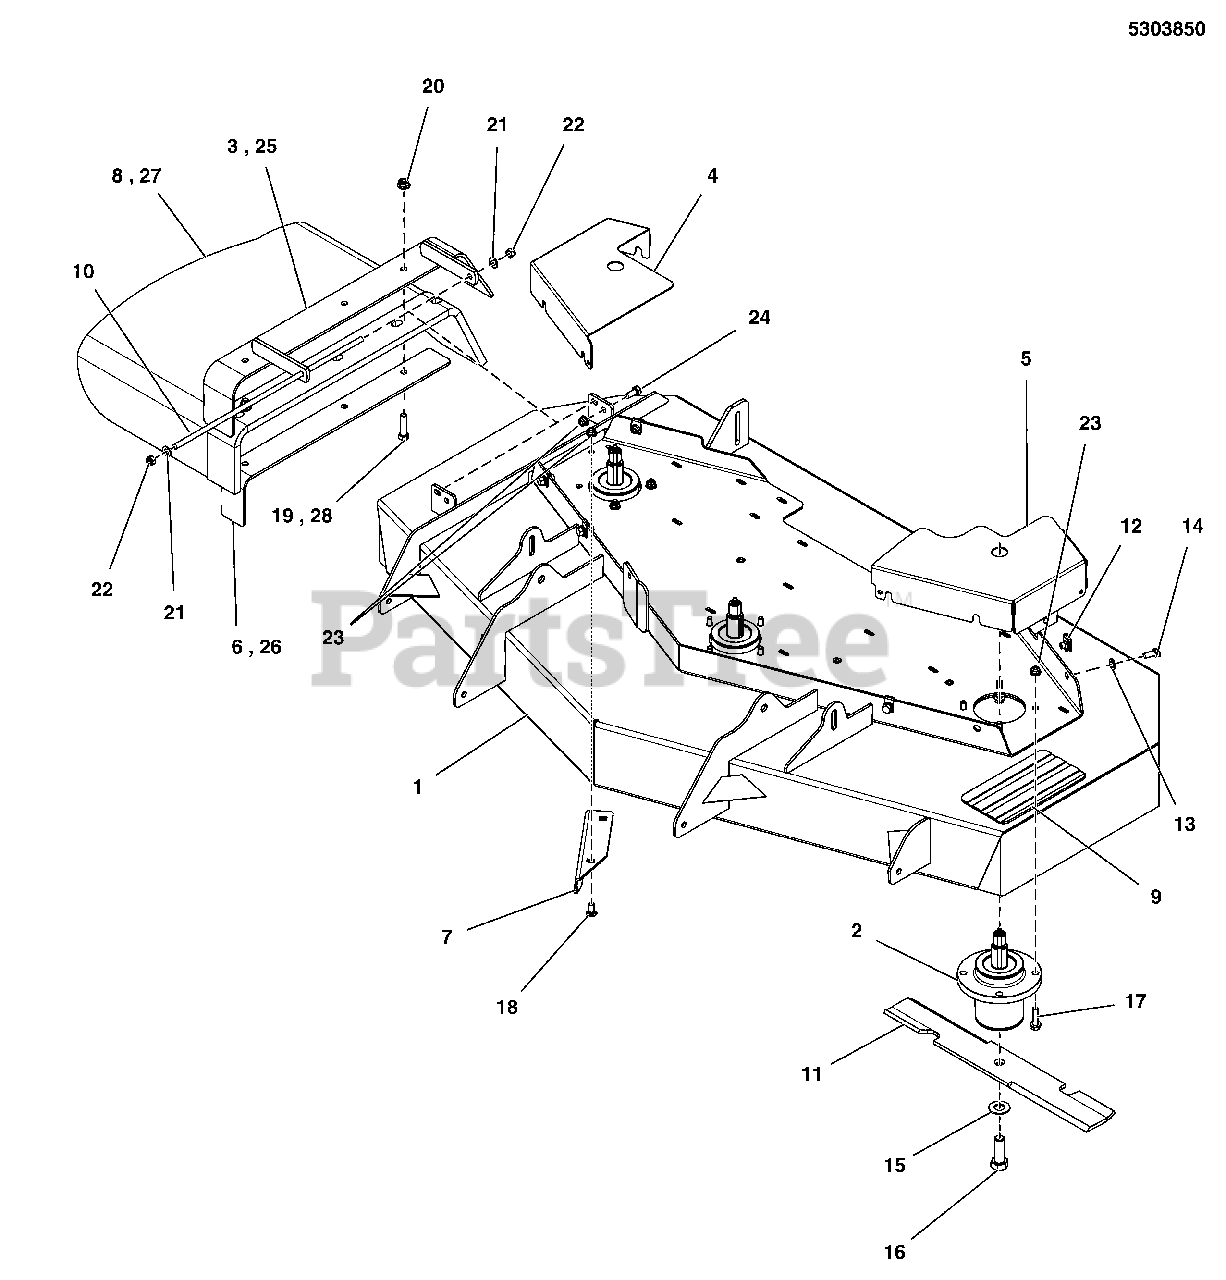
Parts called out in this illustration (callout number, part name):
1	DECK SHELL W/ DECALS, 550-52, DOM
2	ASSM, SPINDLE, LOW PROFILE
3	WELD, FRAME, CHUTE, 52 - BLK
4	GUARD, 52 DECK, RH - RED
5	GUARD, 52 DECK, LH - RED
6	SUPPORT, DISCHARGE CHUTE, 52 - BLK
8	CHUTE,DISCHARGE,RUBBER 29.00-4 HOLE,BENT
9	SAFETY WALK, 4.00 X 7.50
10	MOUNT, Chute
11	BLADE, 18", SET OF THREE (3)(SV)
12	BODY CLIP, 5/16-18-7GA MATERIAL
13	WASHER, 5/16 SAE
14	BOLT, 5/16-18 X 3/4 GD5
15	WASHER, Blade Bolt, 9/16"
16	BOLT, 5/8-11 X 1-3/4 GD8
17	BOLT, 5/16-18 X 1 1/4 FLANGE
18	BOLT, 5/16-18 X 3/4, CARRIAGE
19	BOLT, 3/8-16 X 1-1/2 GD5 CZ
20	NUT, Hex Flange, Nylock, 3/8-16
21	WASHER, 5/16 SAE
22	NUT, 5/16-24 HEX NYLON LOCK
23	NUT, 5/16-18 HEX NYLOCK FLANGE
24	SCREW, Flange, Whiz-Lock, 5/16-18 X 3/4
25	WELD, MOUNT, DISCHARGE CHUTE - BLK
26	SUPPORT, DISCHARGE CHUTE - BLK
27	CHUTE, RUBBER DISCHARGE (5104442)
28	BOLT, 3/8-16 X 1-1/2, CARRIAGE, GD5, CZ
